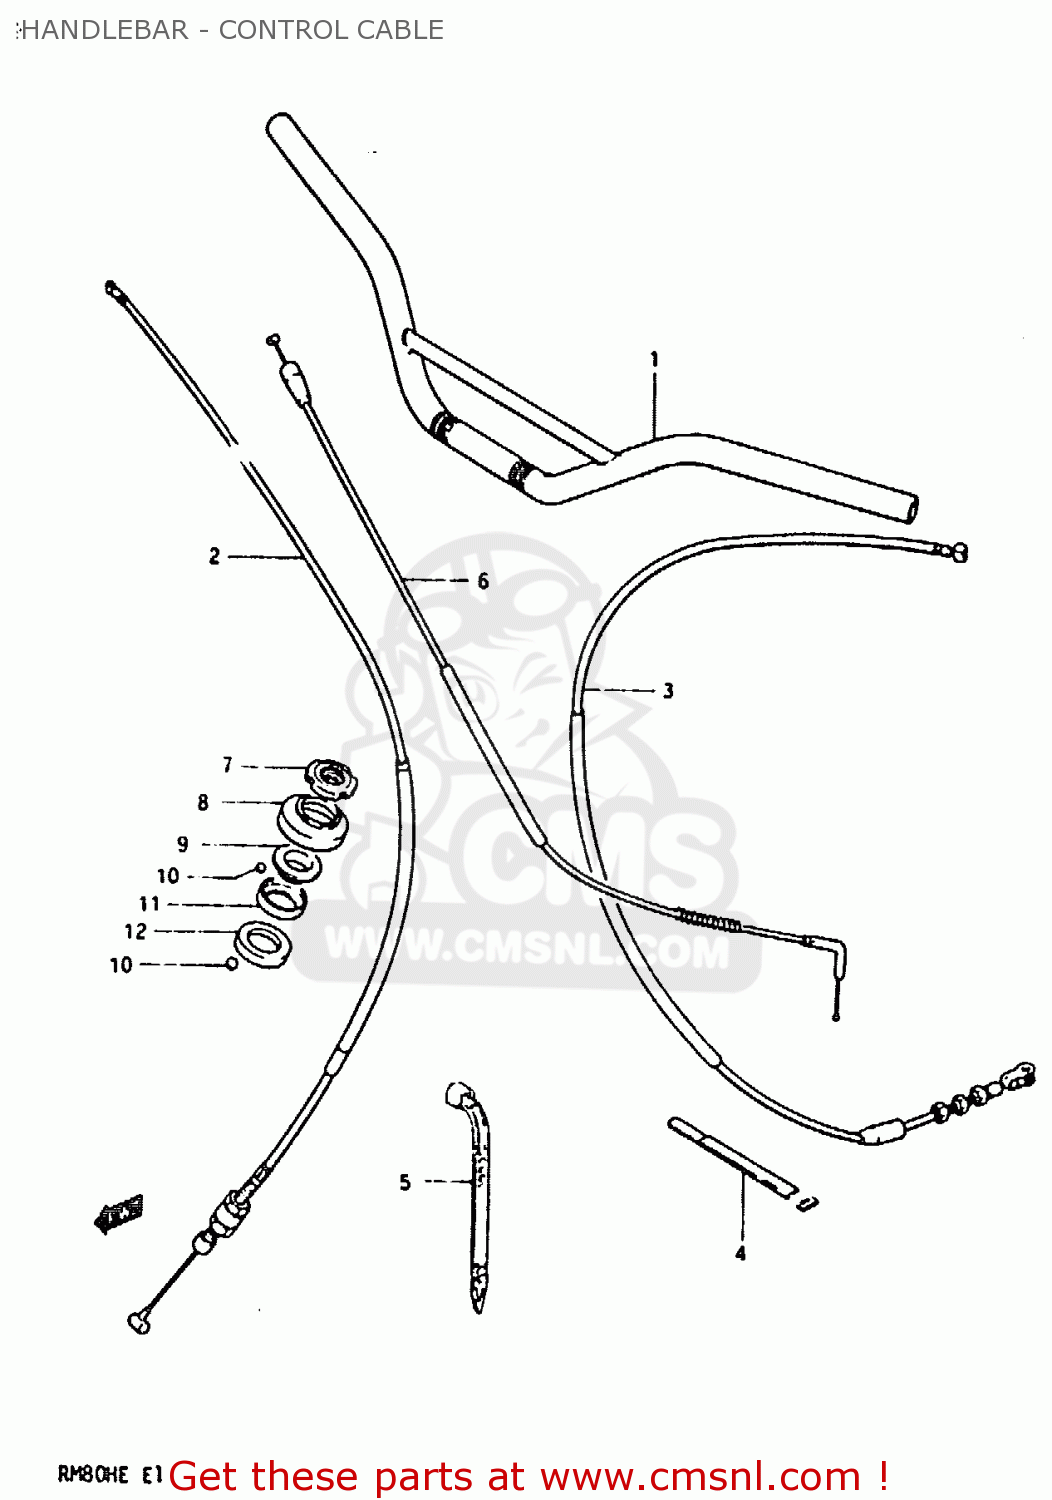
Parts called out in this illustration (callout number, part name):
1	HANDLEBAR (GOLD)
2	CABLE,FR BRAKE
3	CABLE ASSY,CLU
4	CLAMP
5	CLAMP(L:187)
6	CABLE ASSY,THR
7	NUT,STEERING STEM(25X44X10)
8	DUST SEAL, STEERING
9	RACE,STEERING,OUTER,UPPER
10	BALL
11	RACE,STEERING,INNER,UPPER
12	LACE,STEERING INNER LWR
